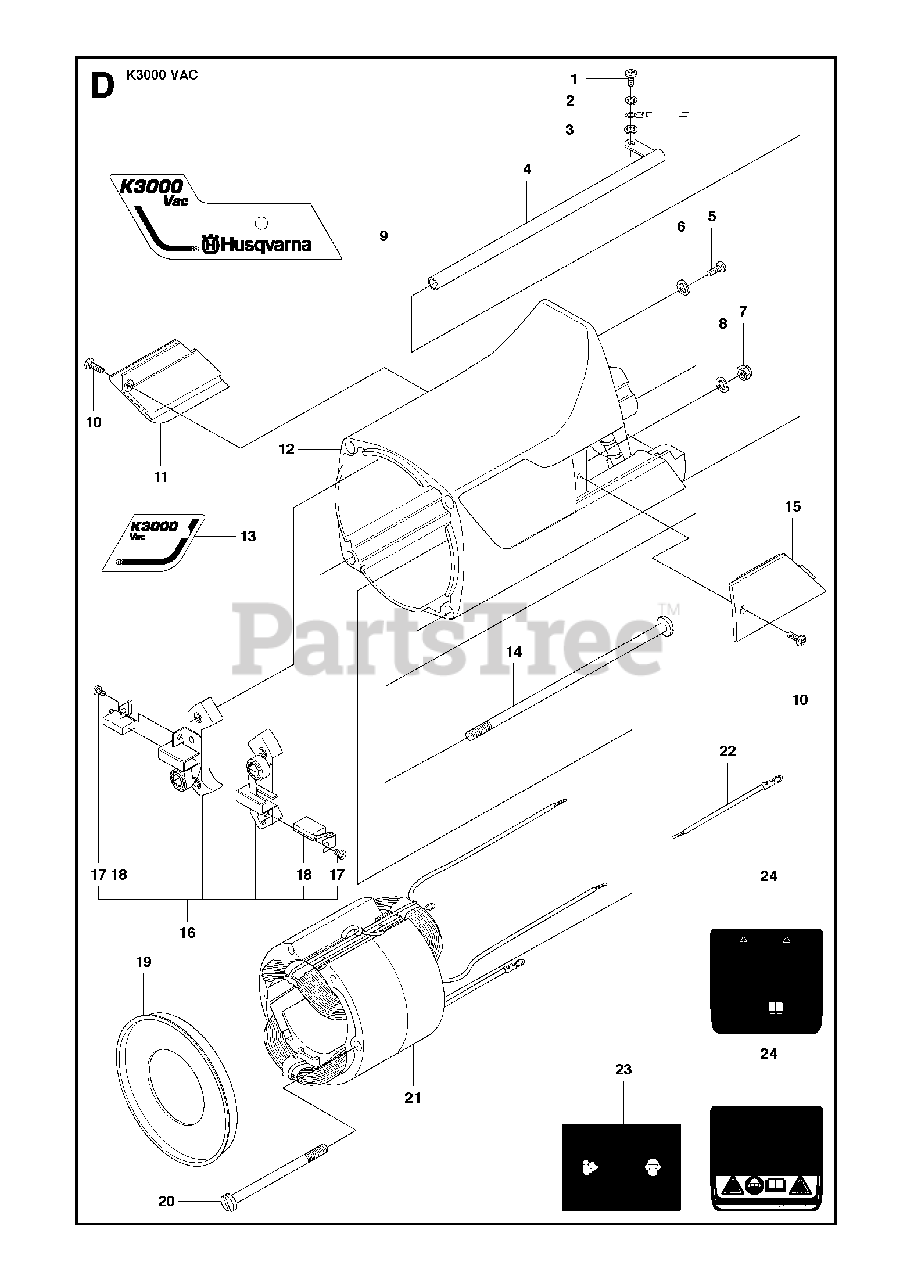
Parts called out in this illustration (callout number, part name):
6	SPRING WASHER
8	SPRING WASHER
10	SCREW CCRPANT
12	MOTOR HOUSING
16	BRUSH HOLDERIncl. 17 - 18
17	SCREW SLPANM
18	CARBON BRUSH
19	AIR STREAM DIRECTOR
21	STATOR ASSY100 - 120V
21	STATOR ASSY230V
22	JOINTING CABLE100 - 120V
24	LABELUSA, UK
